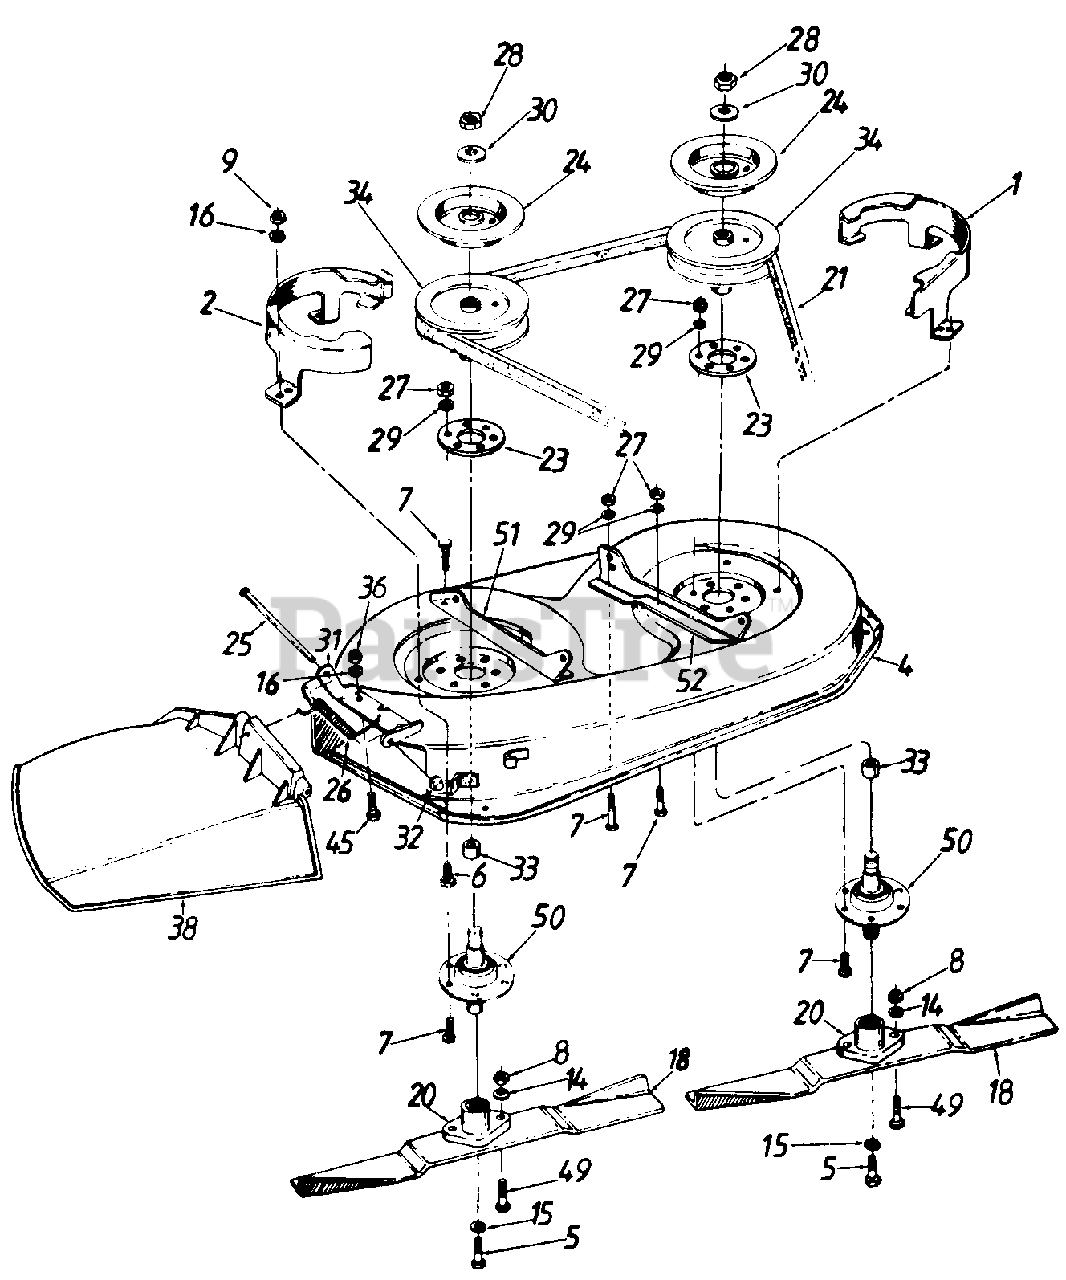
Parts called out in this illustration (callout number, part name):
5	Hex Bolt 3/8-24 x 1.0n Lg.
6	Hex Bolt 1/4-28 x .62n Lg.
7	Hex Bolt 5/16-24 x 75n Lg.
8	Hex Nut 5/16-24 Thd.
9	Hex Nut 1/4-28 Thd.
14	L-Wash. 5/16" I.D.
15	L-Wash. 3/8" I.D. H.D.
16	Bell-Wash. .265" I.D. x .75
18	High-Lift Blade
20	Blade Adapter
21	V-Belt
24	Brake Disc
25	Hinge Pin
26	Torsion Spring
27	Hex Nut 5/16-24 Thd.
28	Hex Jam Nut 5/8-18 Thd.
29	L-Wash. 5/16" I.D.
30	L-Wash. 5/8" I.D.
31	Hinge Mtg. Brkt.
34	5" Dia. Pulley
36	Hex Nut 1/4-20 Thd.
38	Chute Ass'y. Comp.
45	Truss-Mach. Scr. 1/4-20 x .75" Lg.
49	Hex Bolt 5/16-24 x 1.0" Lg.
50	Blade Spindle Complete
51	Deck Bracket-R.H.
52	Deck Bracket-L.H.
